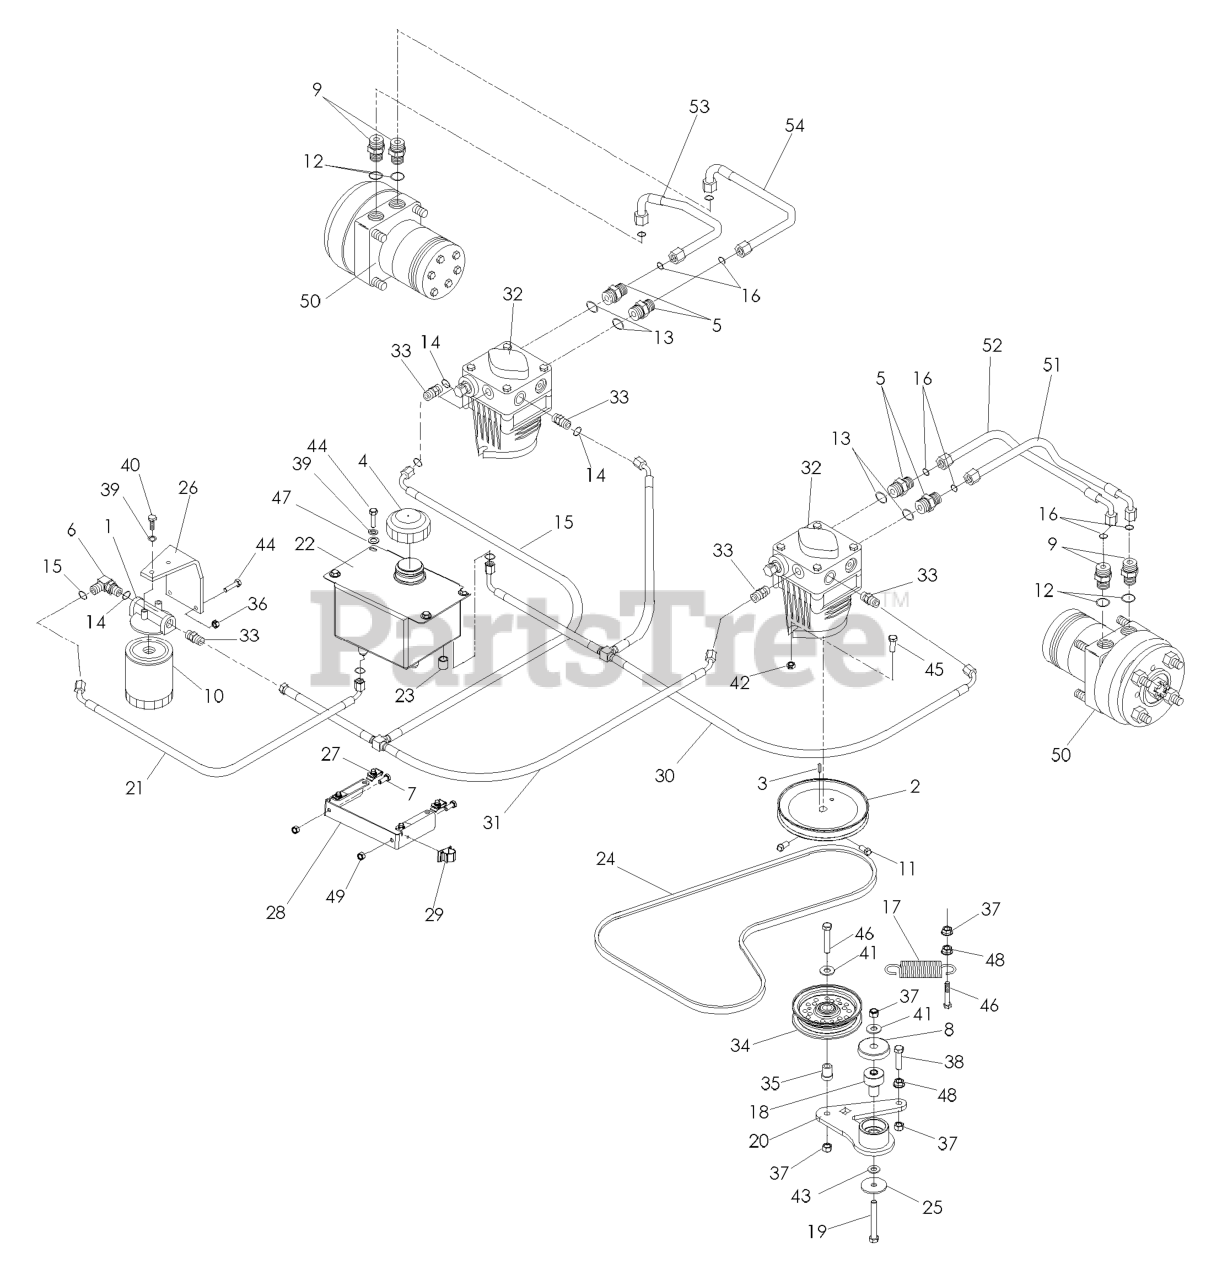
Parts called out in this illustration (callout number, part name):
1	FILTER HEAD
3	KEY 5 MM SQ X 25 MM
4	HYDRAULIC CAP
5	FITTING, STRAIGHT F6400-8-8-0
6	ELBOW, F6801-6-6-0 90 DEGREE
7	HCS 5/16C X 3/4
8	SHIELD, DUST
10	HYDRAULIC OIL FILTER
11	SCREW 5/16C X 5/8 SQ HEAD
18	PIVOT, BEARING
19	HCS 3/8C X 3
20	ARM, IDLER - W/BEARINGS
21	HOSE, TANK - FILTER LINE
23	NUT 9/16-18 JIC CAP
24	PUMP BELT
25	WASHER, 3/8 SPEC
26	OIL FILTER BRKT
27	1/4C - U TYPE RETAINER
28	TANK MOUNT
29	PUSH-MOUNT WIRE CLIP
30	HOSE, T-ASM RETURN
31	HOSE, T-ASM SUPPLY
32	HG_PUMP, 10CC W/O FAN
33	HYDRAULIC FITTING
34	IDLER PULLEY
35	BUSHING, IDLER FLANGE
36	NUT.1/4-20.HEX.NYLOC.ZD
37	NUT 3/8-16 NYLOC
38	HCS 3/8C X 1 1/2
39	LOCKWASHER 1/4"
40	HCS 1/4C X 5/8
41	WASHER 3/8 FLAT
42	NUT 3/8C CENTERBLOCK
43	WASHER 3/8 SAE FLAT
44	HCS 1/4C X 3/4 HCS
45	4CS 3/8C X 1 SERRATED HEAD
46	HCS 3/8C X 2
47	WASHER 1/4 FLAT
48	NUT 3/8C WHIZ
49	NUT 5/16 NYLOC
50	TL15 WHEEL MOTOR
50	WHEEL MOTOR
51	HOSE, RPB - MB, LINE
52	HOSE, RPA - MA LINE
53	HOSE, LPA - MB LINE
54	HOSE, LPB - MA LINE
